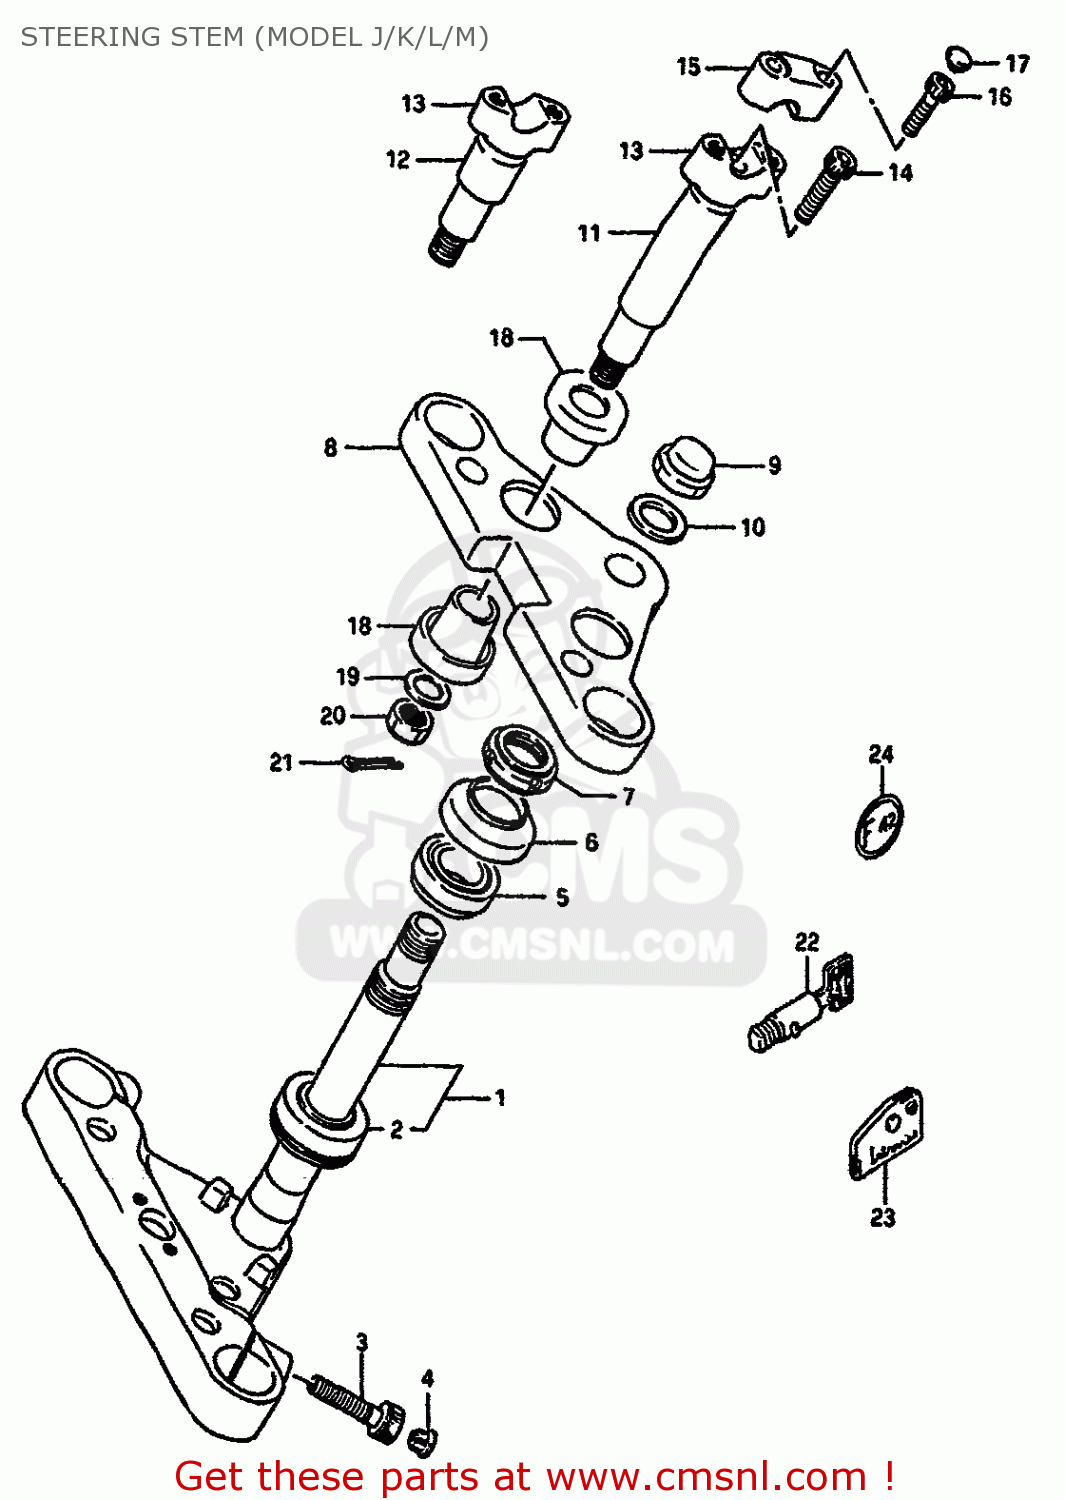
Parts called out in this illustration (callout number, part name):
1	STEM,STEERING
2	BEARING(30X55X17)
3	BOLT,STEERING STEM HEAD
4	CAP(OD:12)
5	TAPER,ROLLER BEARING
6	DUST SEAL,STEERING,UPPER
7	NUT,STEERING STEM(25X44X10)
8	BRACKET,UPR
9	NUT,CAP
10	WASHER
11	STAY,HANDLE
12	STAY,HANDLE
13	HOLDER,HANDLE LWR
14	BOLT
15	HOLDER,HANDLE UPR
16	BOLT, REAR (8X30)
17	CAP(OD:14.5)
18	CUSHION
19	WASHER
20	NUT
21	PIN
22	LOCK SET,STEERING
23	CASE,STEERING KEY
24	LABEL,STEERING LOCK
